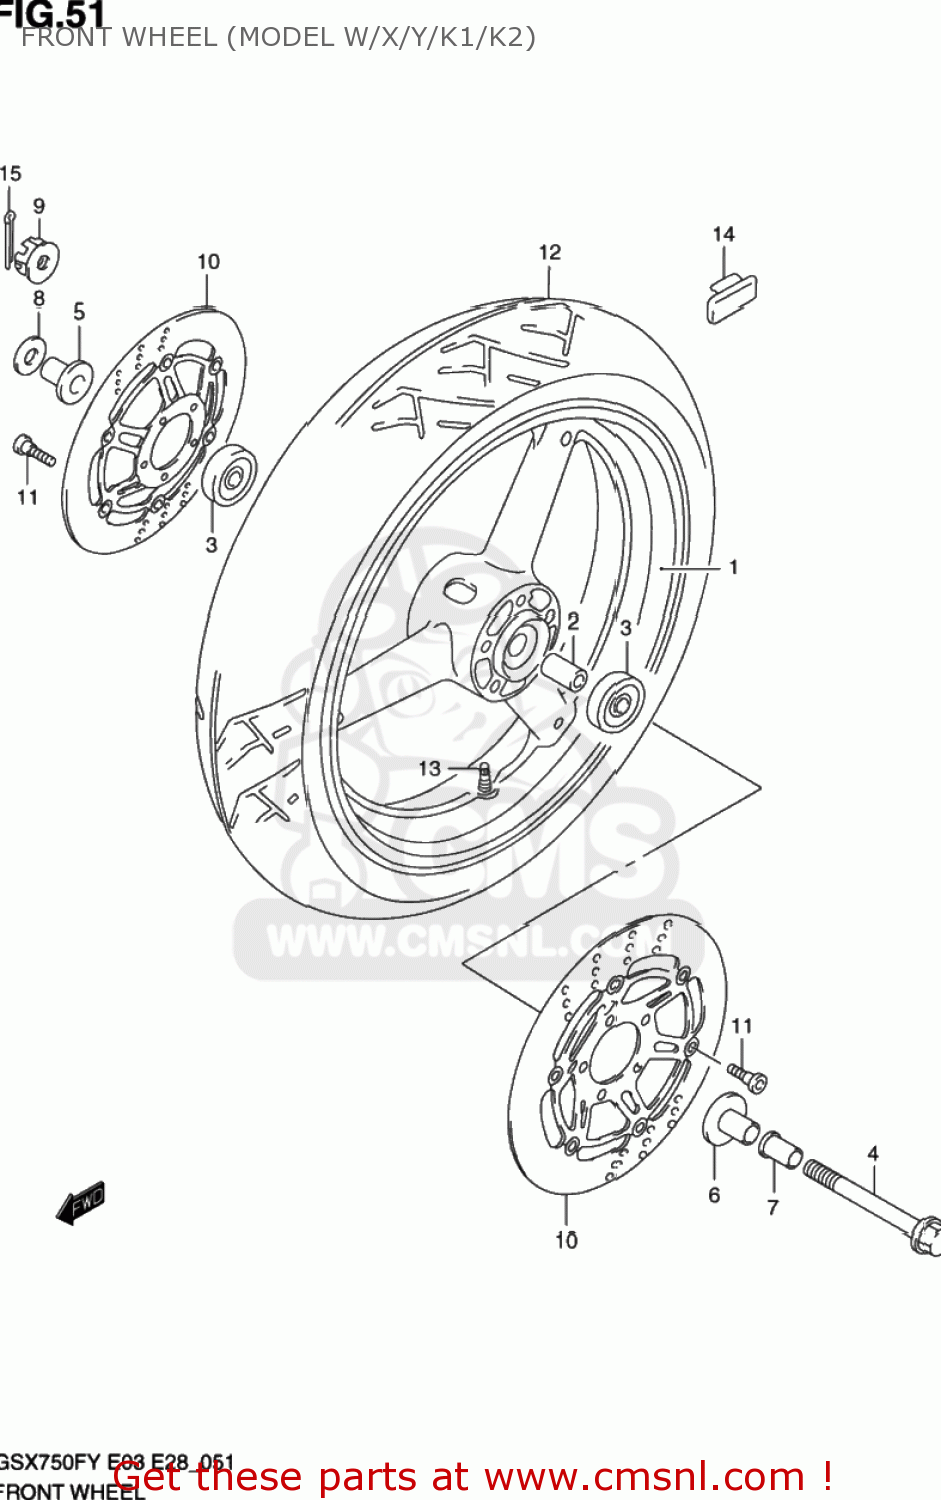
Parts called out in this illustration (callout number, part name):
1	WHEEL,FR(17XMT3.50)
2	SPACER(15.3X21.7X63)
3	BEARING
4	AXLE,FR
5	SPACER,FR AXLE
6	SPACER,FR AXLE,L
7	SPACER,FR AXLE,L
8	WASHER
9	NUT
10	DISC,FR BRAKE
11	BOLT 8X33
12	TIRE,FR(120/70 ZR17 58W)
13	VALVE ASSEMBLY,WHEEL,TR412
14	BALANCER,WHEEL (10G)
15	COTTER PIN
